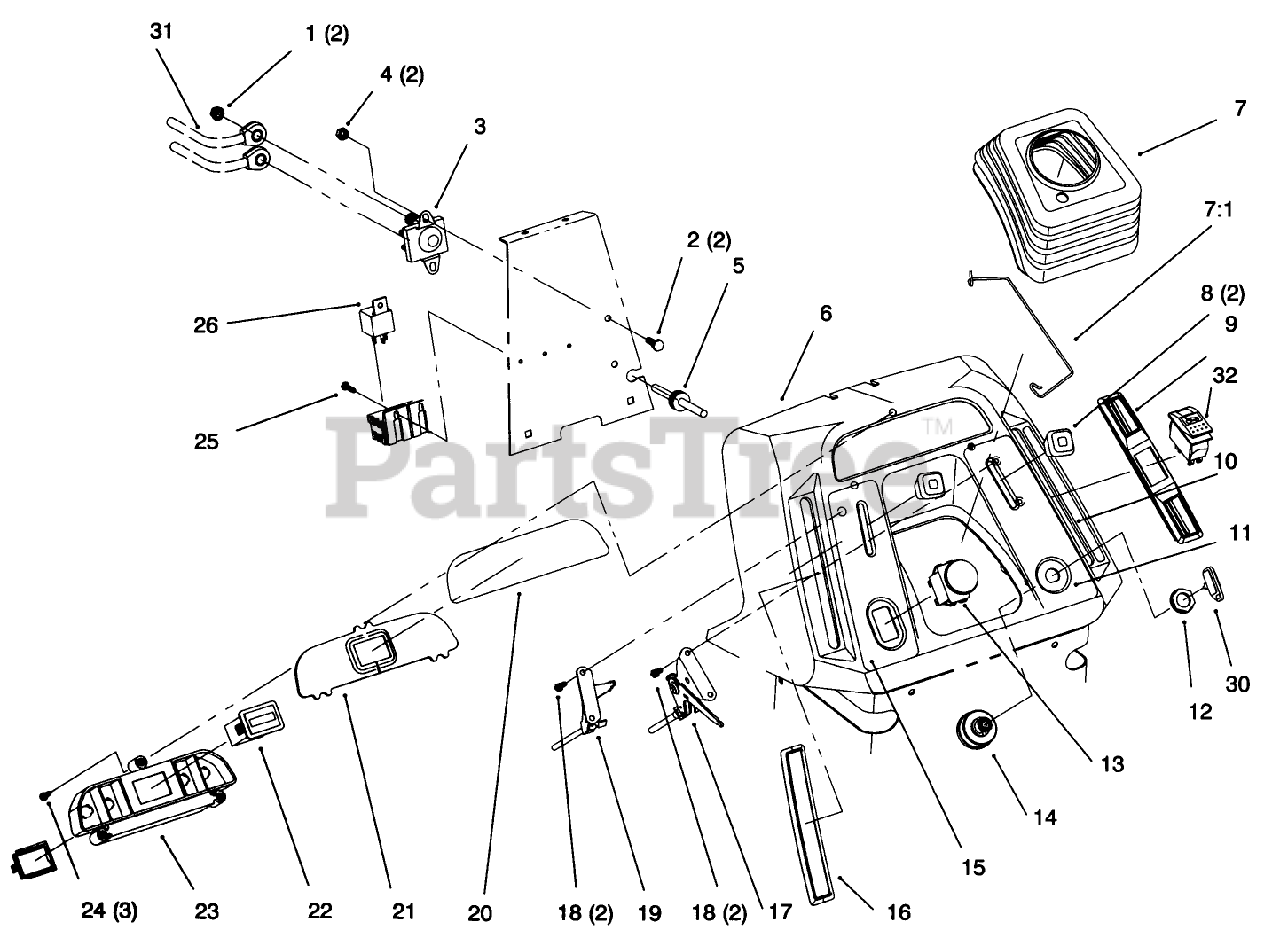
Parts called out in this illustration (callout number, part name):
1	NUT-KEPS
2	SCREW-HH
4	NUT-LOCK, NI
5	GROMMET-RUBBER
7	BOOT-STEERING
7:1	CLIP-BOOT
9	COVER-SLOT, RH
10	DECAL - SHIFT
11	DECAL-THROTTLE, IGNITION
13	SWITCH-PTO,ON-ON-NONE
14	SWITCH-IGNITION
15	DECAL-PTO / CHOKE
15	DECAL - DASH PTO/CHOKE
16	COVER-SLOT, LH
17	CONTROL-THROTTLE
17	CONTROL-THROTTLE (TWIN)
19	CONTROL-CHOKE
19	CONTROL-CHOKE (TWIN)
21	LENS-DASH
23	HOUSING-LIGHT, INDICATOR
24	SCREW-PPH
25	SCREW-PPHTF
26	RELAY
30	KEY-IGNITION
31	WIRE-21 INCH
32	SWITCH-CRUISE
